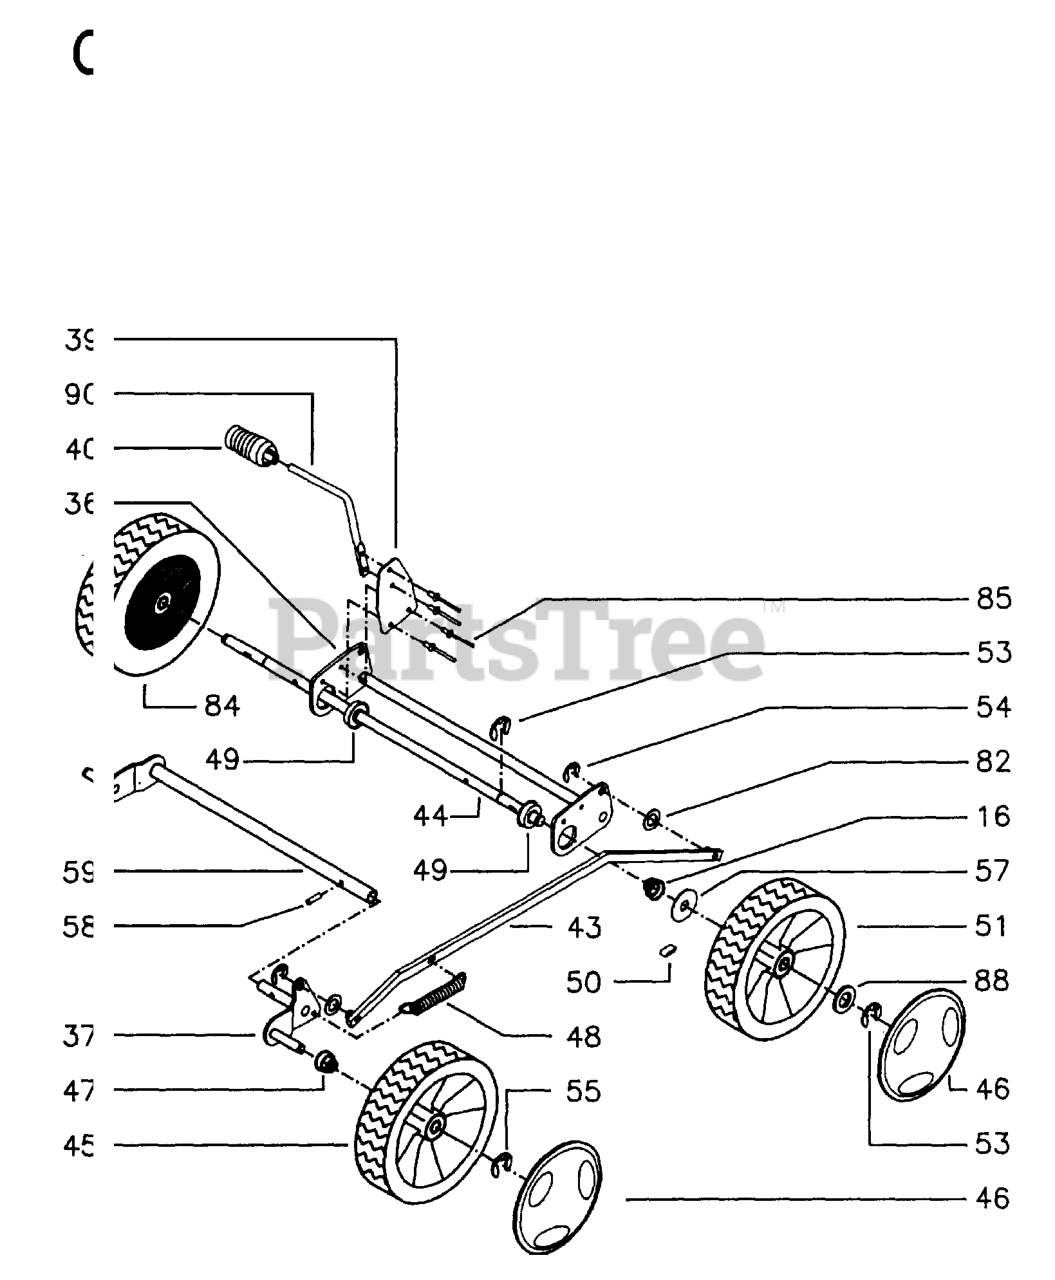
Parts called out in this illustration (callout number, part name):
47	CONE SPRING
50	CARRIER
85	REPL BY 516 92 38-00
